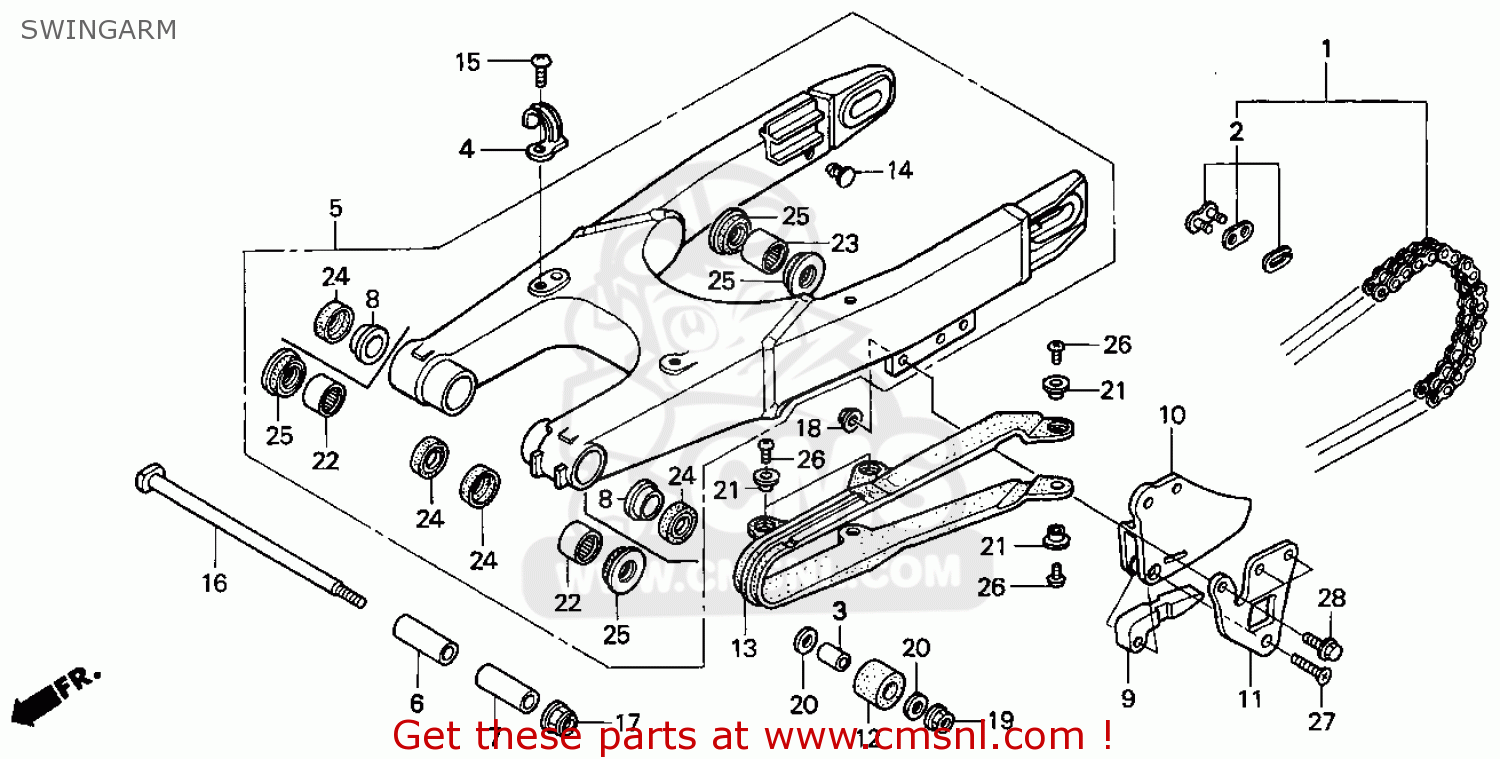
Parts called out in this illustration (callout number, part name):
1	CHAIN,DRIVE
2	JOINT,DRIVE CHAIN
3	COLLAR,LINK
4	GUIDE,RR BRK HOSE
5	SWINGARM ASSY,RR
6	COLLAR,SWINGARM R
7	COLLAR,SWINGARM L
9	SLIDER,CHAIN GUID
10	GUIDE
11	PLATE,CHAIN GUIDE
12	ROLLAR,CHAIN TENS
13	SLIDER,CHAIN
14	PLUG,RR.FENDER
15	SCREW,PAN,5X10
16	BOLT,SWINGARM PIV
17	NUT,FLANGE,14MM
18	NUT,U.,6MM
19	NUT,FLANGE 8MM
20	WASHER 8MM
21	WASHER,HDLP.SET
22	NEEDLE BRG
23	BRG,NEEDLE,20X26X
24	DUST SEAL,20X26X4
25	DUST SEAL,20X26X4
26	SCREW,CROSS 5X12
27	SCREW,FLAT,6X35
28	BOLT,FLANGE,6X22
